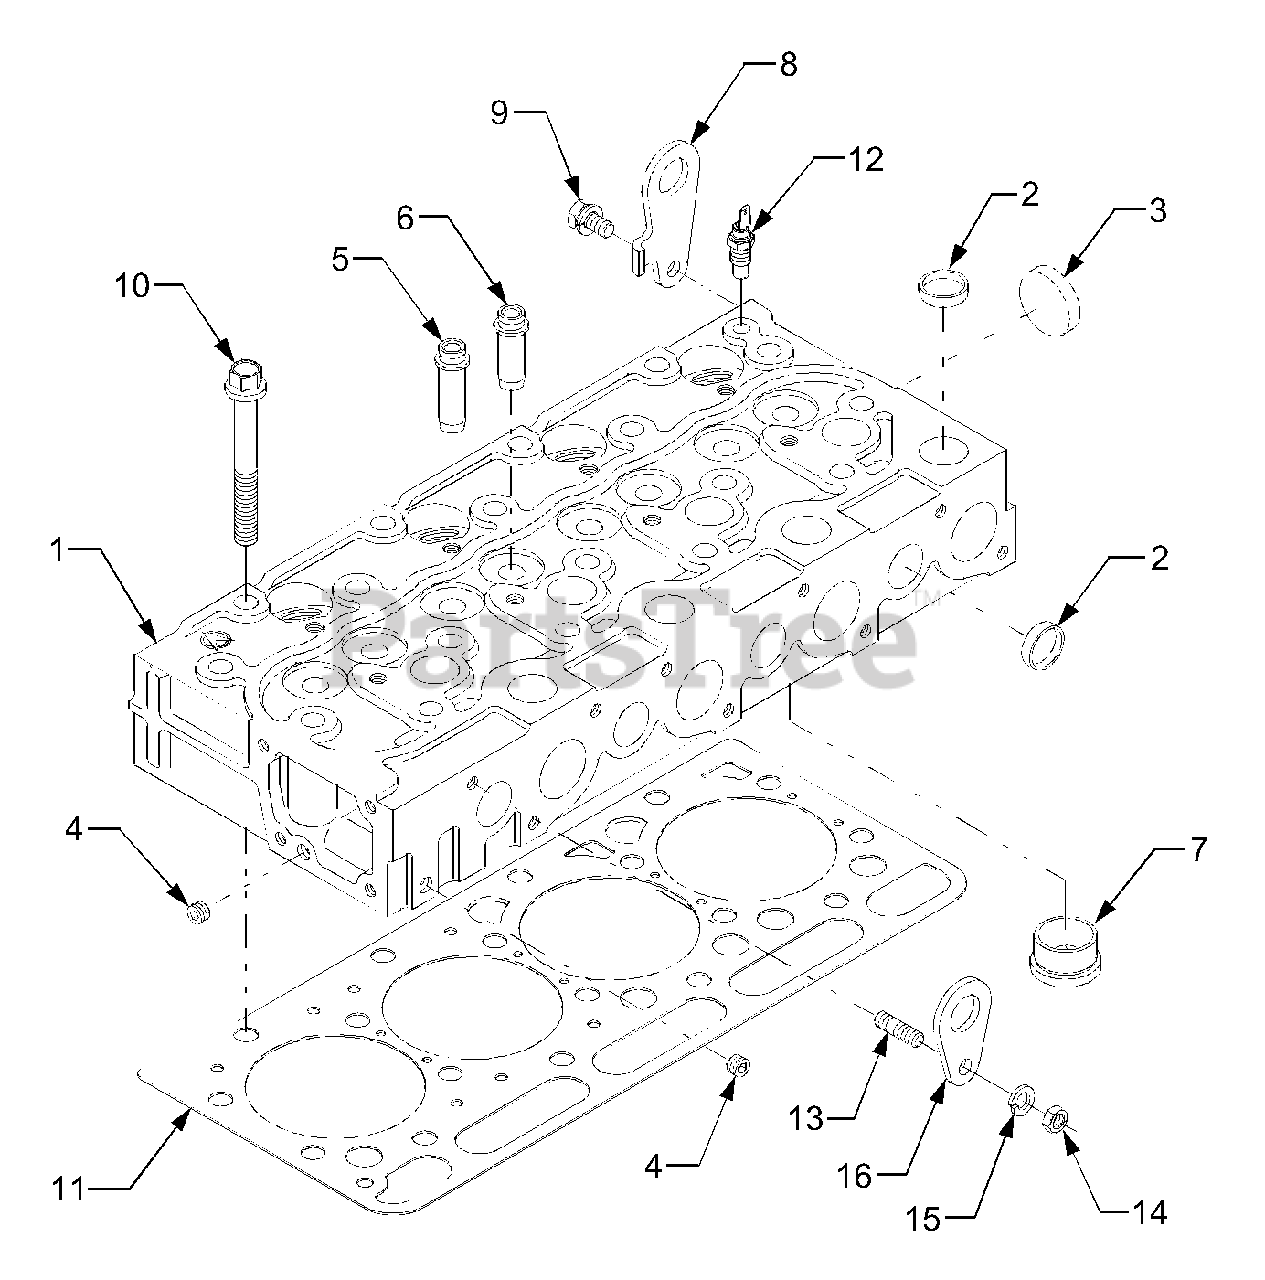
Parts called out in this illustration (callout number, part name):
1	Cylinder Head Ass'y
5	Guide, Inlet Valve
6	Guide, Outlet Valve
10	Bolt, Cylinder Head
11	Gasket, Cylinder Head
12	Switch, Thermostat
15	Washer, Spring
